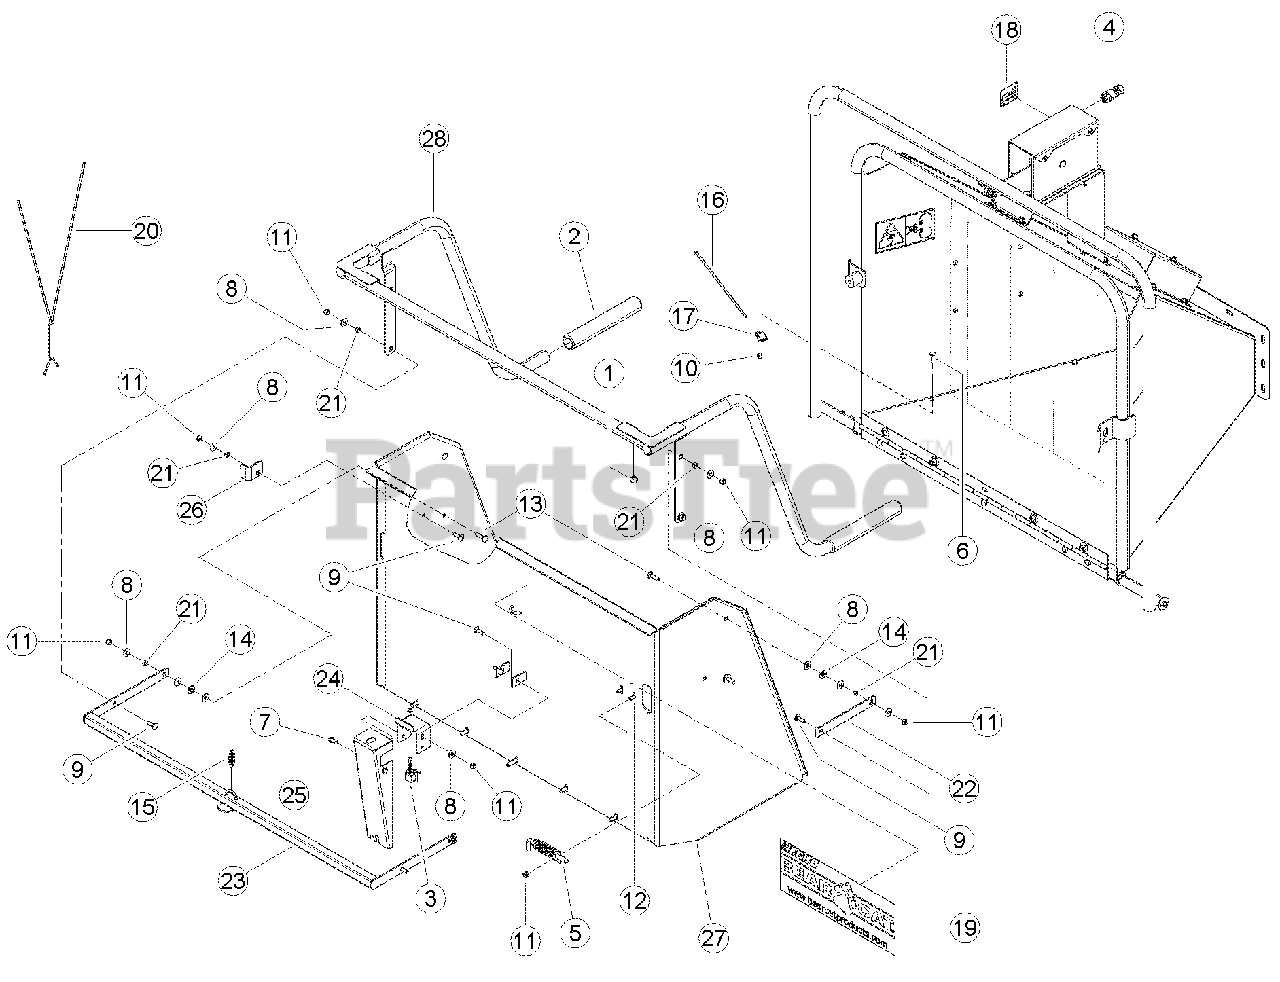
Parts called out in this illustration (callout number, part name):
1	BUMPER, RUBBER
2	GRIP, 1.219 X 10.00
5	LATCH, RH HINGE
6	BOLT, 1/4 X 1 HEX HD GR5 ZP
7	SCREW, 11/32 X 7/8 HWH AB THREAD ZP
8	WASHER, 5/16 FLAT ZP
9	BOLT, 5/16 X 1 CRG GR5 ZP
10	NUT, 1/4 NE NYLOCK ZP
11	NUT, 5/16 NE NYLOCK ZP
12	BOLT, 5/16 X 3/4 CRG GR5 NC ZP
13	BOLT, 5/16 X 1-1/4 CRG GR5 ZP
14	WASHER, 5/16 ID X 7/8 OD NYLON FLAT
15	SPRING, 1/2 X 2.00 LG ZP
16	STRAP, 11 IN. BLACK TIE
17	CLAMP, CABLE MOUNT
18	DECAL, RESET/OVERRIDE
19	DECAL, BEARCAT WEB
20	HARNESS, SAFETY BAR
21	SPACER, IDLER PIVOT
22	LINK, PARALLEL
23	WELDMENT, KNEEBAR PIVOT
24	BRACKET, SWITCH
25	SHIELD, KNEEBAR SWITCH
26	LOCK, SAFETY BAR
27	WELDMENT, EXTENSION TRAY W/ TABS
28	WELDMENT, KNEEBAR
